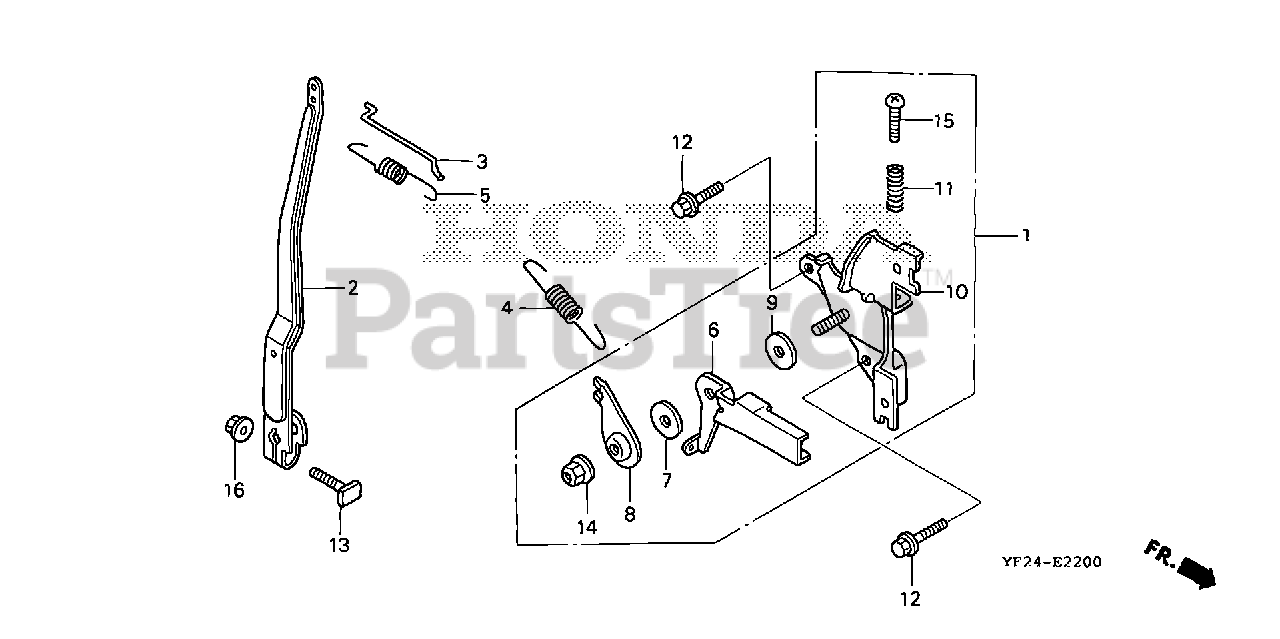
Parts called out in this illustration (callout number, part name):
1	CONTROL ASSY.
2	ARM, GOVERNOR
3	ROD, GOVERNOR
4	SPRING, GOVERNOR
5	SPRING, THROTTLE RETURN
6	LEVER, CONTROL
7	SPRING, LEVER
8	WASHER, CONTROL LEVER
9	SPACER, CONTROL LEVER
10	BASE, CONTROL
11	SPRING, CONTROL ADJUSTING
12	BOLT, FLANGE (5X12)
13	BOLT, GOVERNOR ARM
14	NUT, SELF-LOCK (6MM)
15	SCREW, PAN (5X20)
16	NUT, FLANGE (6MM)
